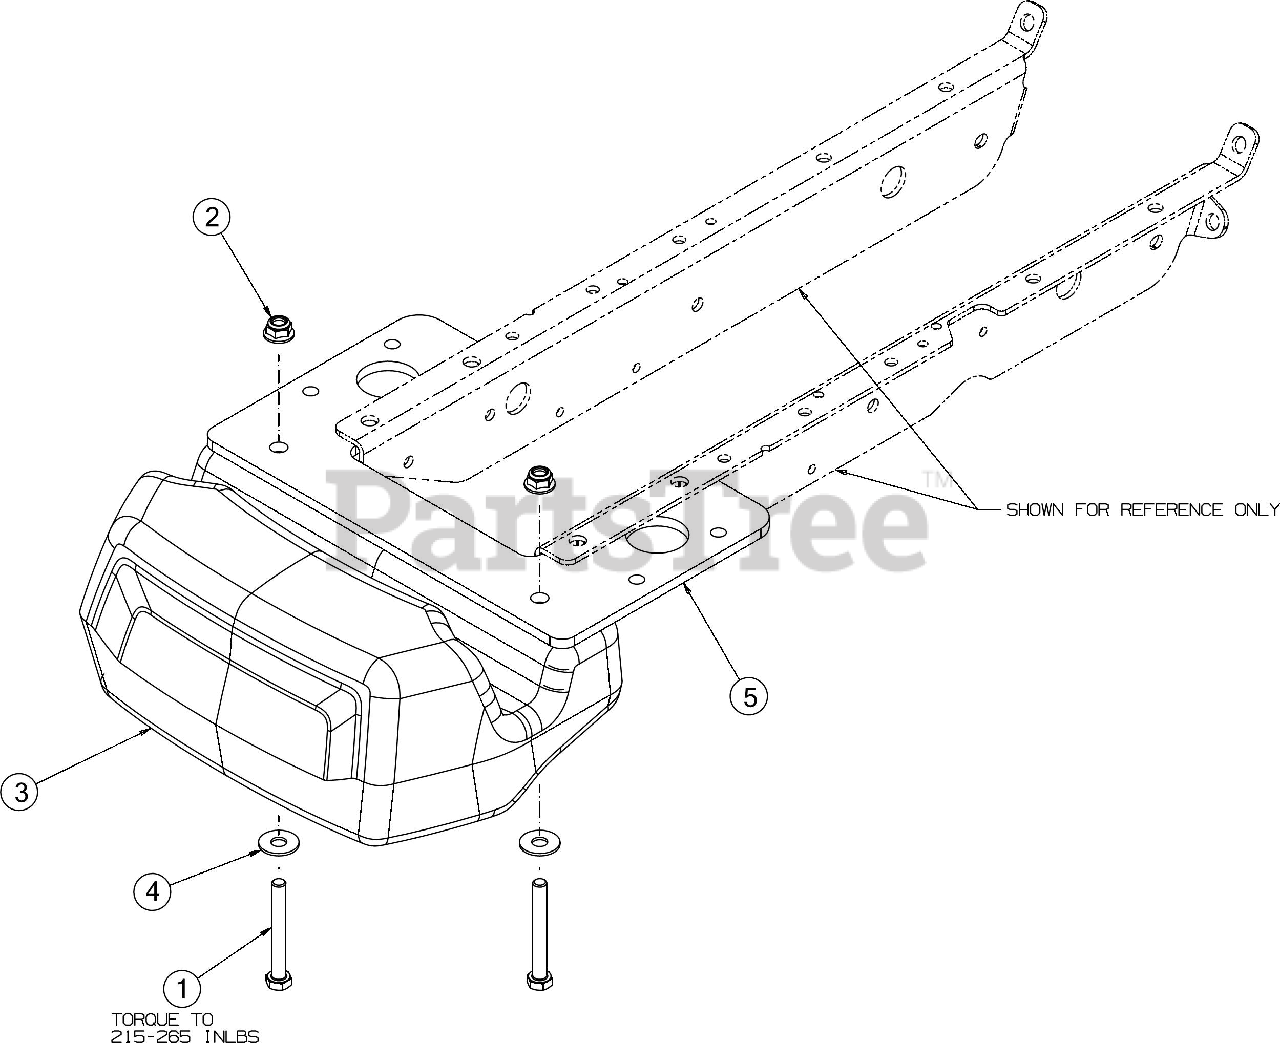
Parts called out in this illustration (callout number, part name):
1	SCREW 5/16-18 x 2.5 GR 5
2	FLANGE LOCK NUT 5/16-18
3	COUNTERWEIGHT
4	FLAT WASHER
5	BUMPER MOUNTING PLATE
